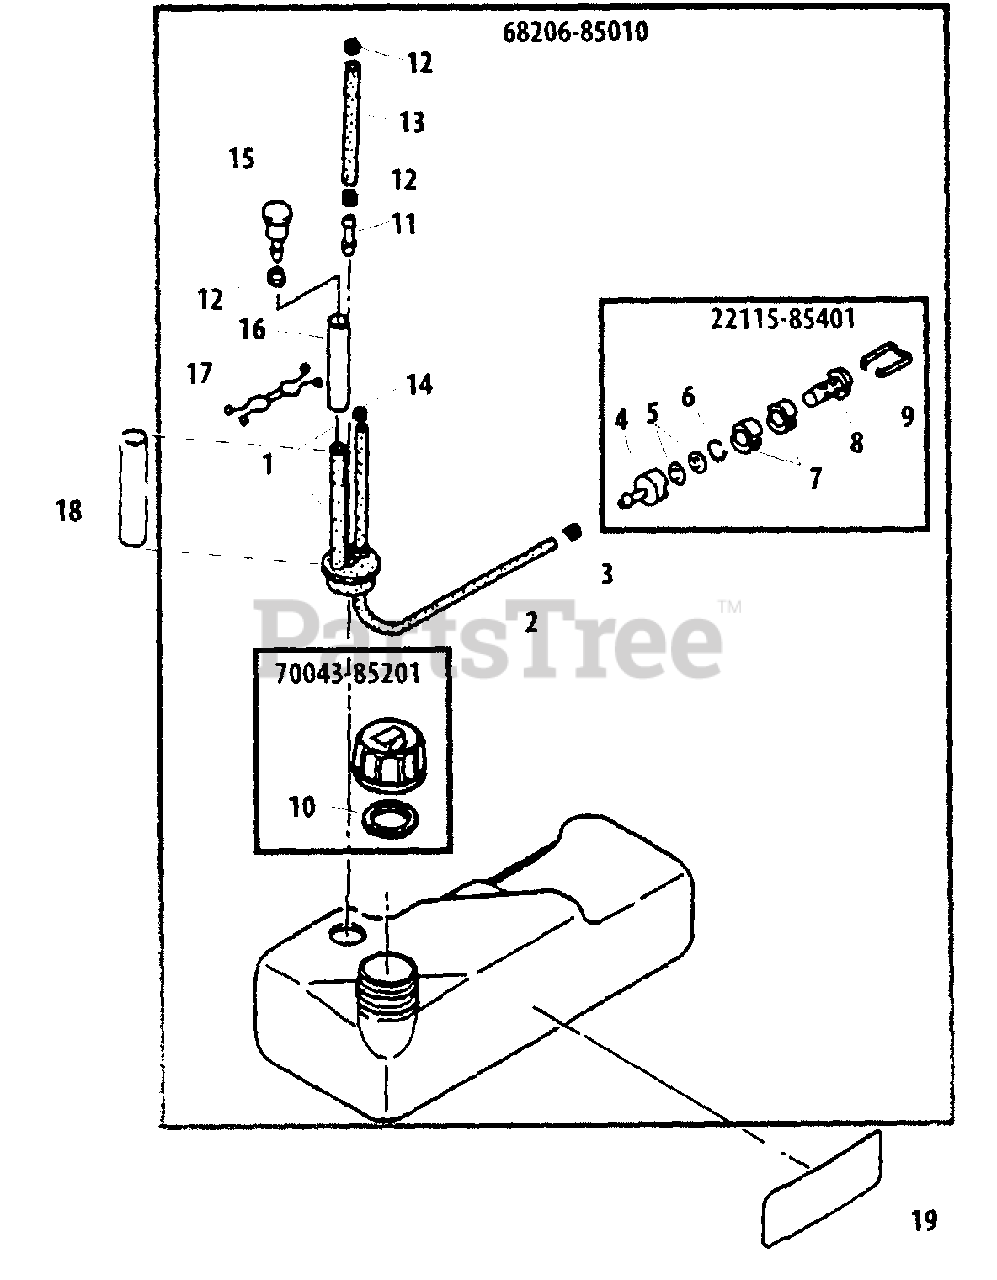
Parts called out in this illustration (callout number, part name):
1	GROMMET, FUEL W/VENT PIPE
2	TUBE
3	CLIP Ø6
4	WEIGHT, FUEL LINE
5	SCREEN, FILTER
6	RING, RETAINING
7	FILTER, FUEL
8	BODY, FUEL FILTER
9	CLIP, FILTER
10	GASKET, FUEL CAP
11	CONNECTOR, PIPE
12	CLIP Ø6
13	PIPE Ø5ר3×L110
14	CLIP
15	VENT ASSY
16	TUBE, INSULATOR
17	CLIP
18	TUBE, INSULATOR
19	NAME LABEL
22115-85401	FILTER, FUEL
68206-85010	FUEL TANK ASSY
70043-85201	CAP ASSY, FUEL
